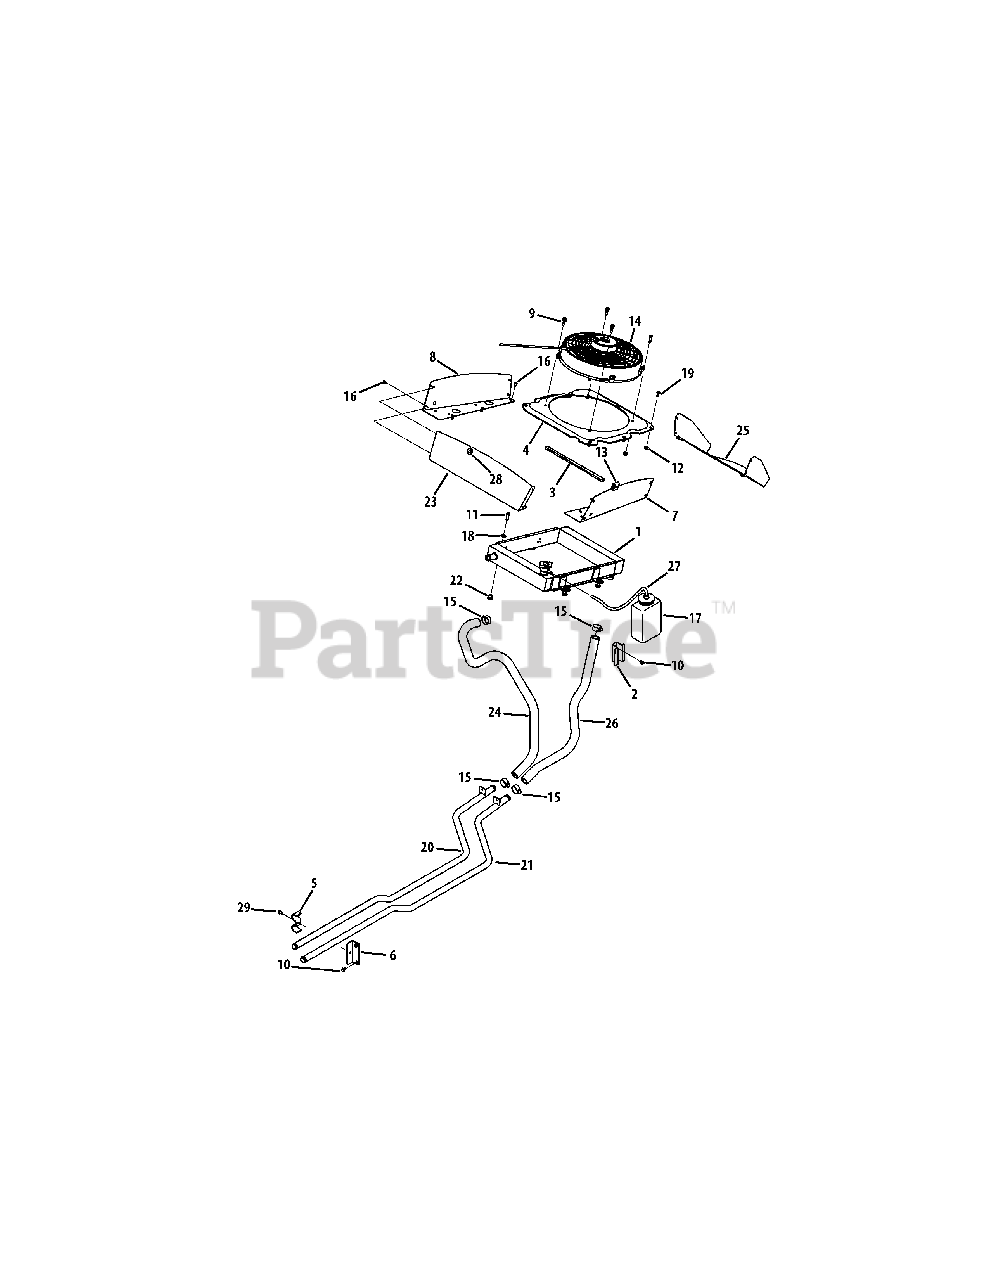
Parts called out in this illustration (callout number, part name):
1	Radiator Assembly, zin Core
3	Tape, .625 Wide x .25 Thk Foam
4	Shroud, Fan, Mount
9	Hex Head Screw, 1/4-20 x 1.00, gr5
10	Screw, tt, 1/4-20 x 0.500, hxindwsh
11	Screw, tt, 1/4-20 x 1.000, hxindwsh
12	Nut, Flange Lock, 1/4-20, Nylon
13	Heat Baffle Seal
14	Fan, electric, 12v, w/Guard, Yan
14	Fan, electric, 12v, w/Guard,Koh EFI
15	Clamp, hose, adj
16	Pop Rivet 3/16 Dia x .450, sty1
17	Container, Over Flow, coolant
18	Washer, flat, .28 x .74 x .063
19	Screw, 1/4-20 x .620
20	Tube, inside, rdtr 4x4
21	Tube, outside, rdtr 4x4
22	Spacer, Step
24	Hose, radiator, frt 4x4
25	Shroud, front
26	Hose, radiator, frt 4x4
27	Tube, overflow, radiator
28	Grommet, Rubber
29	Screw, tt, 1/4-20 x .750
